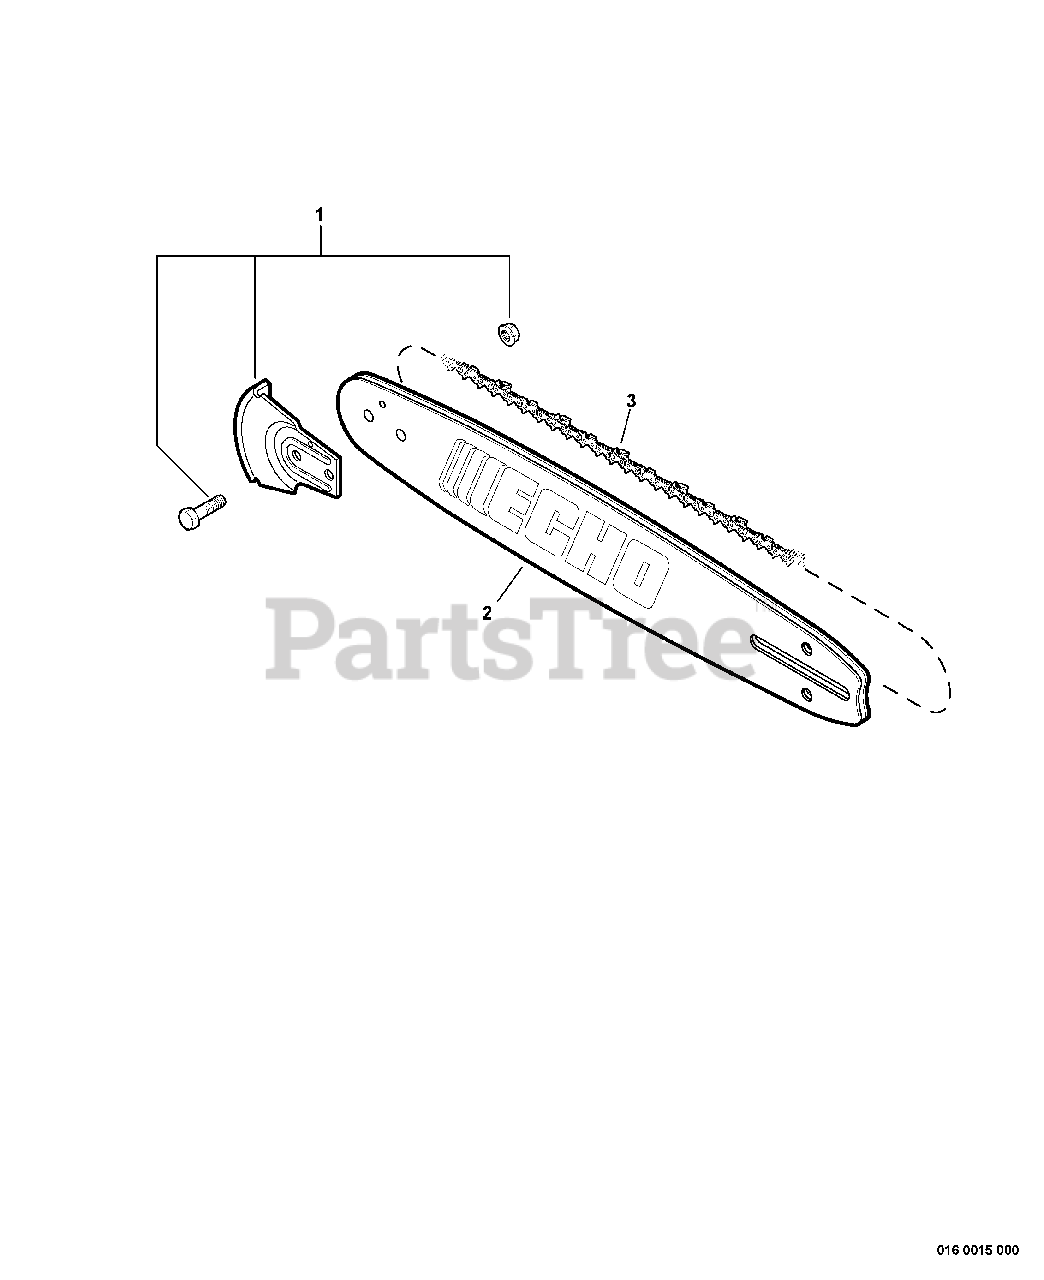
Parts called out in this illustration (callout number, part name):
1	KICK GUARD KIT
2	GUIDE BAR, 20" DOUBLE-GUARD
3	SAWING CHAIN - 20" -- PRO GUARD
